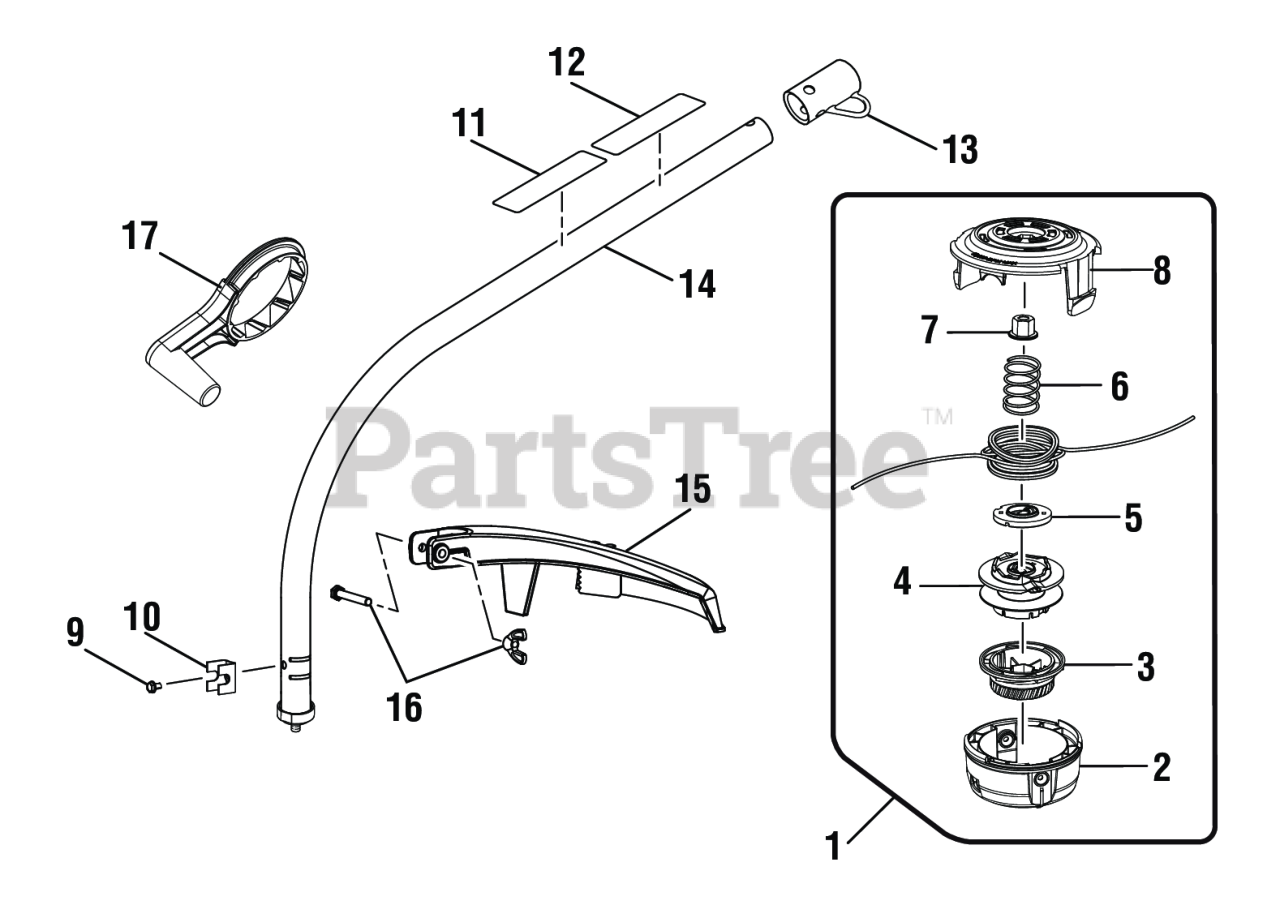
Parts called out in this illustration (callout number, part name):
1	Trimmer Head Assembly (.095)
2	Lower Housing
3	Bump Knob (Green)
4	Spool Assembly
5	String Guide
6	Compression Spring
7	Flange Nut (M8)
8	Upper Housing
9	Screw (#10-32 x 3/8 in., Hex Washer Hd. S.T.)
11	Ryobi EXPAND-IT Label
12	Warning Icon Label
13	Storage Hanger Cap
14	Curved Shaft Assembly
15	Grass Deflector Assembly
16	Fastener Parts Kit
17	Crank Handle Assembly
